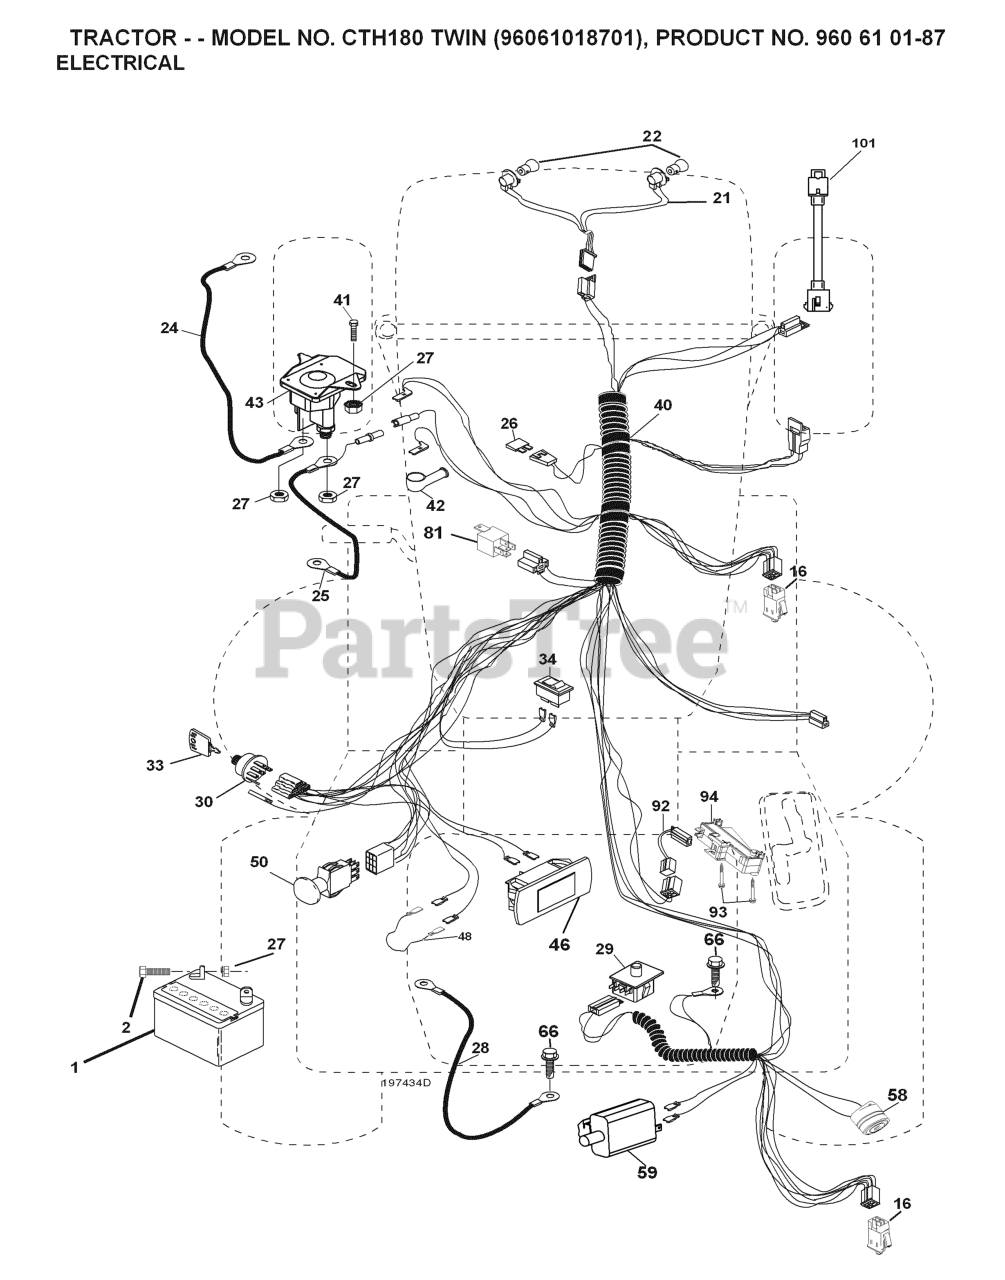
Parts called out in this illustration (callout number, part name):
1	BATTERY 12V .35 AMP
2	BOLT.HEX.1/4.X.3/4.DICHROMATE
16	SWITCH INTERLOOK PUSH-IN
21	HARNESS ASSY LIGHT
24	BATTERY CABLE GT
25	CABLE BATTERY
26	FUSE 20AMP
27	NUT
28	CABLE GROUND
29	SWITCH.SEAT.DP W/RAMPS
30	SWITCH.IGN.DELTA.W.LGH.ROS
33	KEY MLD GEN DELTA
40	RP HARNESS.IGN.ELECT.REG.CRD
41	BOLT
42	TERMINAL COVER
43	SOLENOID.W/BRASS.PLUNGER
46	RP.GUAGE.SRVCMNDR.HRMTR.
48	ADAPTER.AMMETER
50	RP.PTO.SWITCH.8 TERMINAL.BLACK
58	BUZZER
59	.WITCH.FULL BAGGER.INDICATOR
81	RELAY.ASSY.T
92	HARNESS.PIGTAIL.CONSLE
93	SCREW.PLASTITE
94	MODULE.REVERSE.ROS
101	PIGTAIL.MATNLK.NEW.HAR
